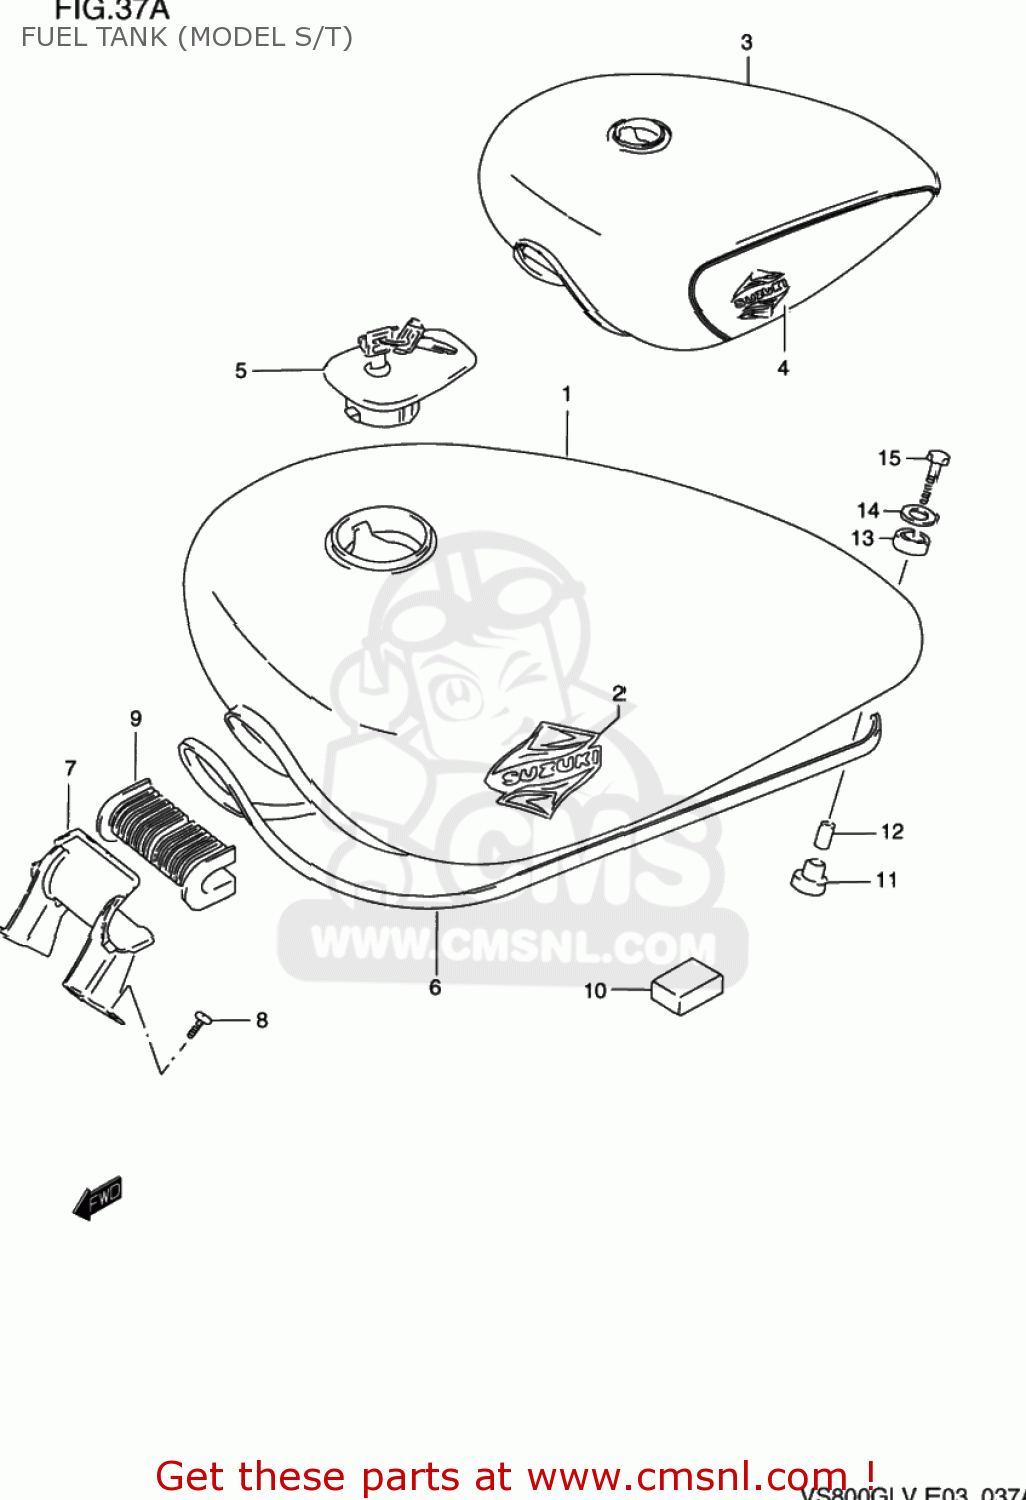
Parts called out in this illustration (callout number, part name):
1	TANK ASSEMBLY,FUEL
2	EMBLEM,FUEL TANK
3	TANK ASSEMBLY,FUEL
4	TAPE SET,FUEL TANK
5	CAP SET,FUEL TANK
6	MOLDING,FUEL TANK
7	BRACKET,FUEL TANK FR
8	SCREW
9	CUSHION,FUEL TANK FR
10	CUSHION
11	CUSHION
12	SPACER (6.4X9X21.5)
13	CUSHION
14	WASHER (6.5X24X1.6)
15	SCREW
